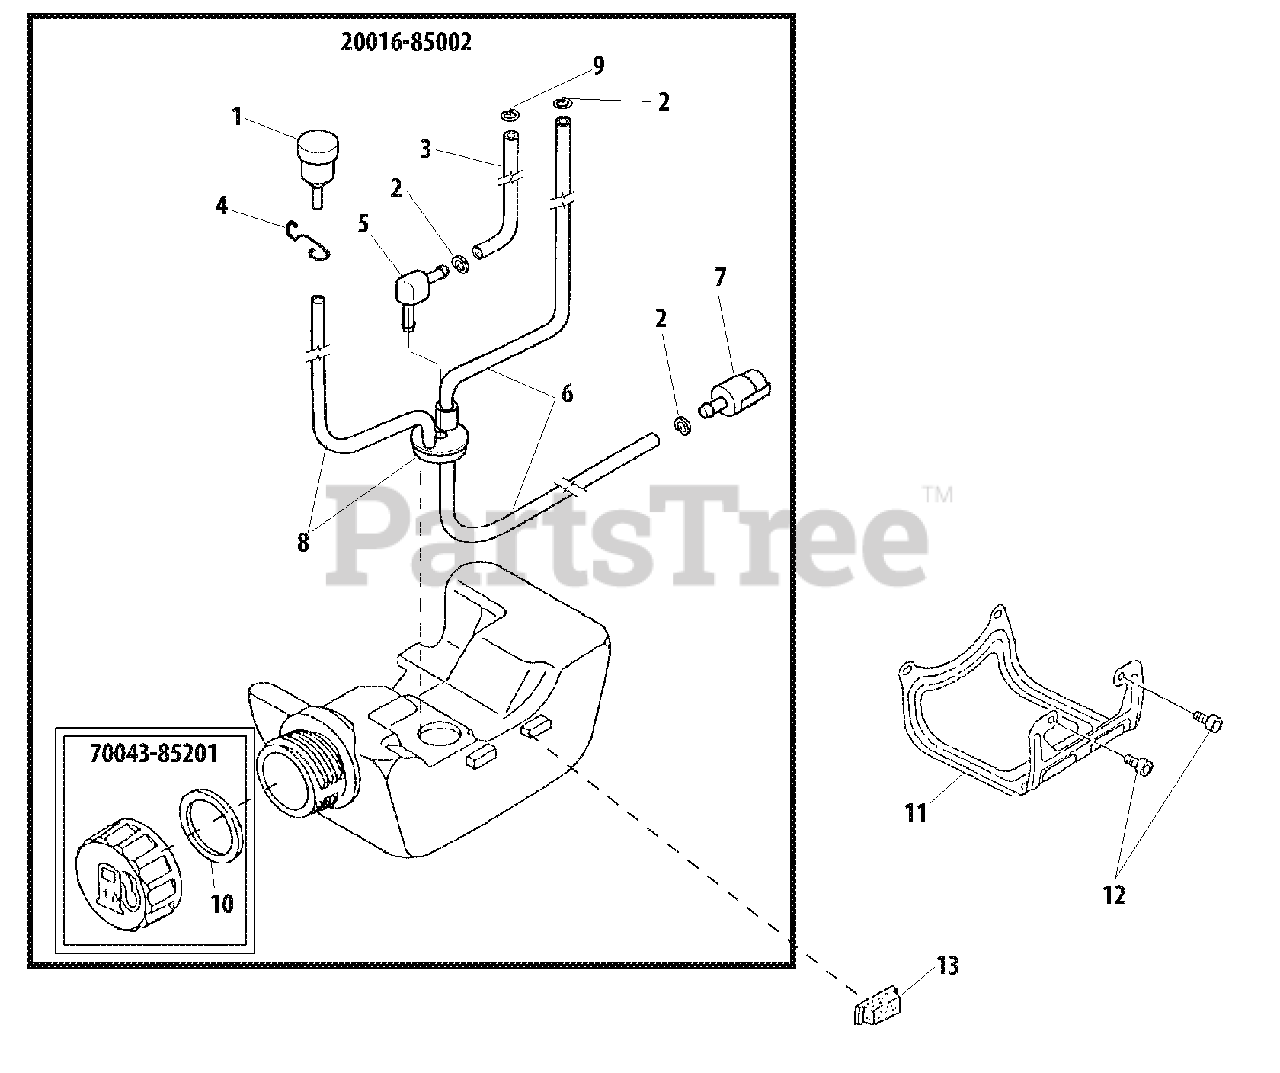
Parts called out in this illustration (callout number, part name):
1	VENT, FUEL TANK
2	RING, RETAINING - 6
3	PIPE - RETURN
4	HOLDER, VENT
5	CONNECTOR, PIPE
6	PIPE - FUEL
7	FILTER, FUEL
8	GROMMET
9	CLIP - SPRING
10	GASKET, CAP
11	GUARD, FUEL TANK
12	SCREW - 5X12
13	CUSHION, TANK
20016-85002	FUEL TANK ASSY
70043-85201	CAP ASSY
